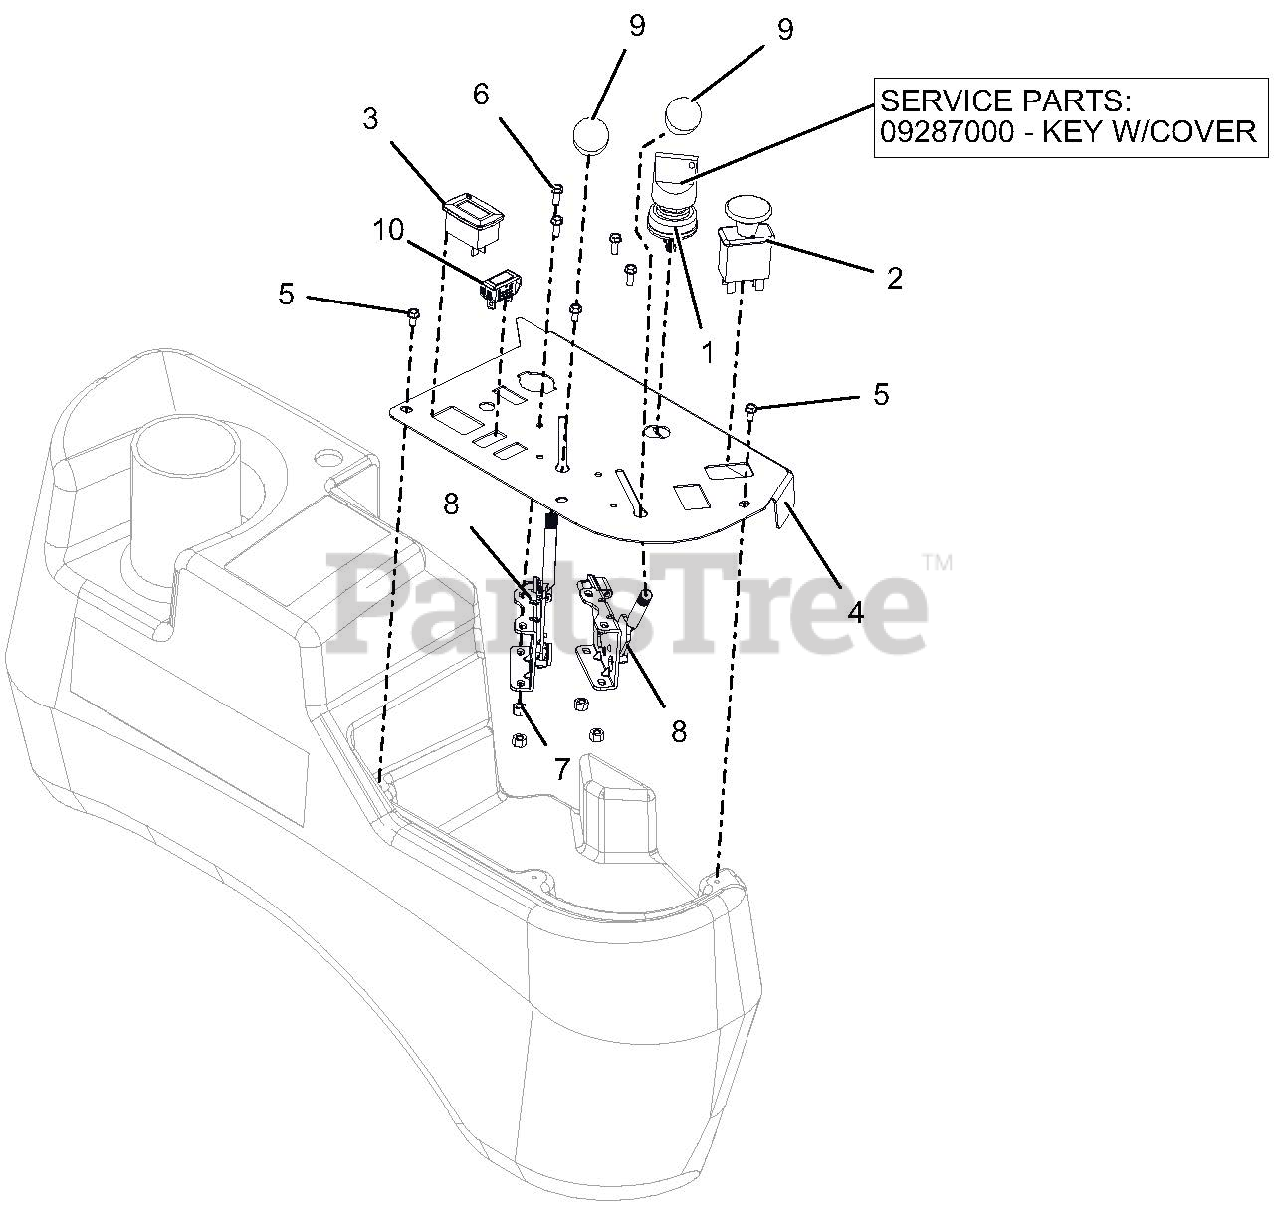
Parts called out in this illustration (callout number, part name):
1	SWITCH, IGNITION
1	KEY W/COVER
2	SWITCH, CLUTCH
3	METER, HOUR W/MAINTENANCE
4	PANEL, CONTROL
5	SCR-MCH 10-24X.38 HWHSTAINLESS
6	@SCR-MCH 10-24X.50 HWH YWZC
7	NUT-LK-NYL #10-24 YWZC
8	CABLE, PRO-CONTROL THROTTLE
9	KNOB, CONTROL BLACK .38-16X.50
10	LIGHT, INDICATOR
